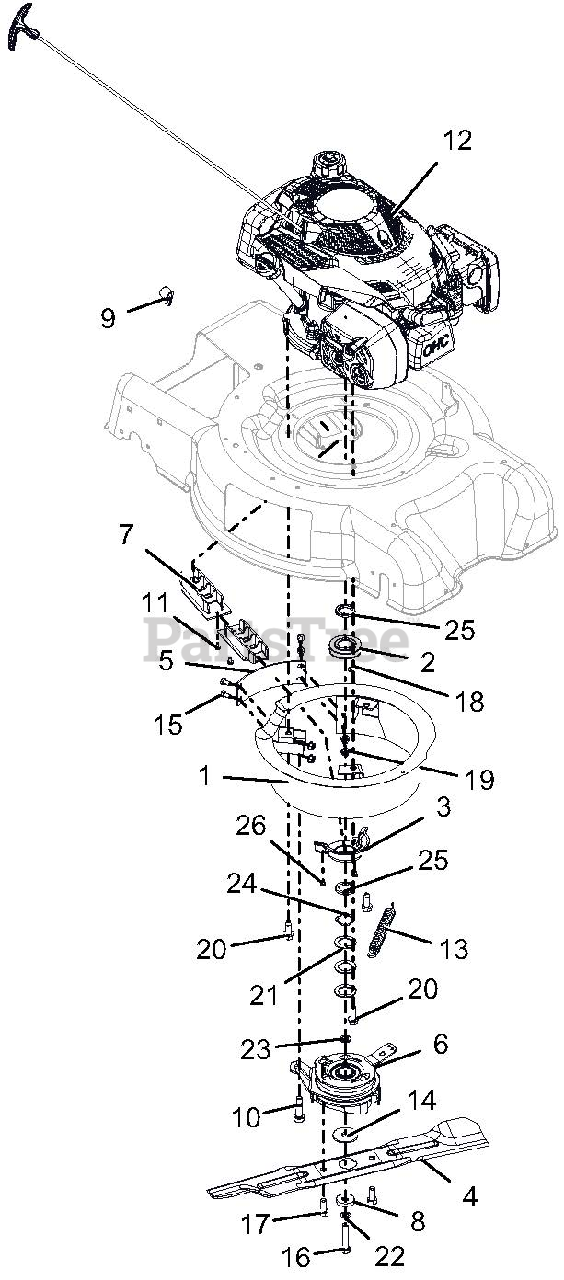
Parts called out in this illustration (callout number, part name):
1	WLDMT, ENCLOSURE - BBC
2	PULLEY, MACHINED POWDER METAL
3	GUIDE, BELT CRANKSHAFT
4	BLADE, MOWER 21" HIGH LIFT-BBC
5	BAFFLE, BBC
6	CLUTCH, RAZOR BBC
7	GUIDE, BELT INNER
8	WASHER-FLAT-STL, .44 X 1.25 X .25 YWZC
9	CLAMP, LM CABLE
10	BLT, SHLDR 12MM X 25 W/M10 THD
11	SCR, TAP 10-24X.375 PRE-COAT 80
12	ENGINE, SUBARU 175CC VERT BBC
13	SPRG, EXTENSION BBC
14	WSHR-FL-STL .469X1.75X.10 YWZC
15	BLT-HEX .25-20X.50 GR5 YWZC
16	BLT-HEX .44-20X2.00 GR5 YWZC
17	BLT-HEX M10 X 1.5X20 GR5 YWZC
18	KEY-SQ .188X.188X.250
19	NUT, LK-TOP-FLG .25-20 YWZC
20	SCR-TAP .38-16X1.00 HWH TR YZ
21	WSHR-FL-STL 1.010X1.505X.062 YWZC
22	WSHR-FL-STL .450X.750X.033 YWZC
23	WSHR-FL-STL .459X.750X.105 YWZC
24	WASHER, WAVE
25	SPCR, 1.00 X 1.375 X .179
26	SCR-TAP 10-24X.25 CRSLPH TR YZ
